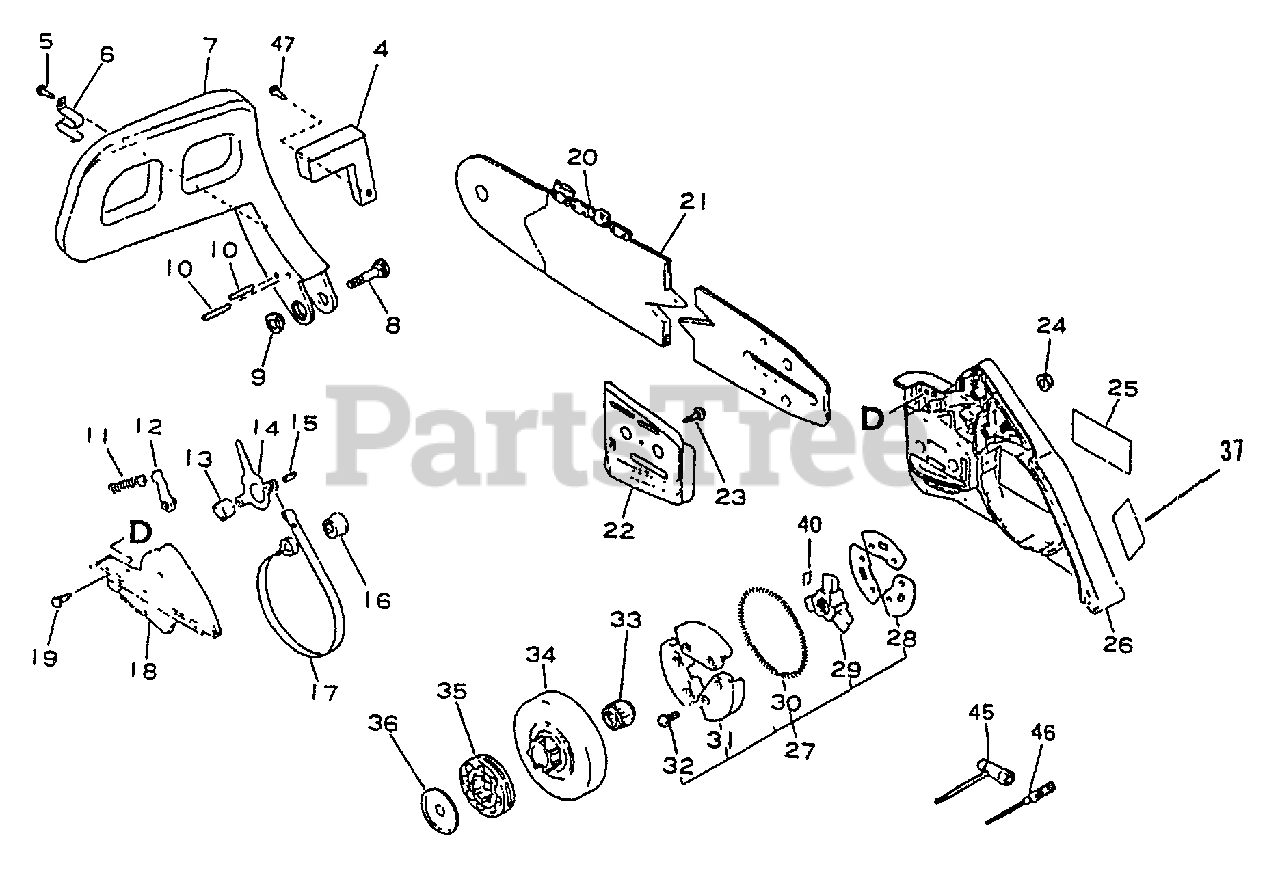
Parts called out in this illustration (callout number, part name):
4	WEIGHT, BRAKE
5	SCREW - 5X14
6	SPRING, RETURN
7	LEVER, BRAKE
10	PIN - 3X24
11	SPRING, BRAKE
12	STOPPER, BRAKE
13	SPACER - 8
14	LEVER, BRAKE
15	PIN - SPRING -- 4X8
16	ADJUSTER, BRAKE BAND
17	BAND, BRAKE
18	COVER, BRAKE
19	SCREW - 4X14
20	SAW CHAIN - 16" (40cm)
20	SAW CHAIN - 18" (45cm)
21	GUIDE BAR - 16" (40cm)
21	GUIDE BAR - 18" (45cm)
22	PLATE, GUIDE - INNER
23	SCREW - 4X8
24	NUT - FLANGE
25	LABEL - ECHO
26	GUARD, SPROCKET
27	CLUTCH ASSY
28	PLATE, CLUTCH
29	HUB, CLUTCH
30	SPRING, CLUTCH
31	CLUTCH SHOE SET
32	SCREW - 4X8
33	BEARING, NEEDLE
34	DRUM, CLUTCH
35	SPROCKET, RIM
37	LABEL - ECHO
45	T-WRENCH - 13X19mm
46	SCREWDRIVER
47	SCREW - 4X14
